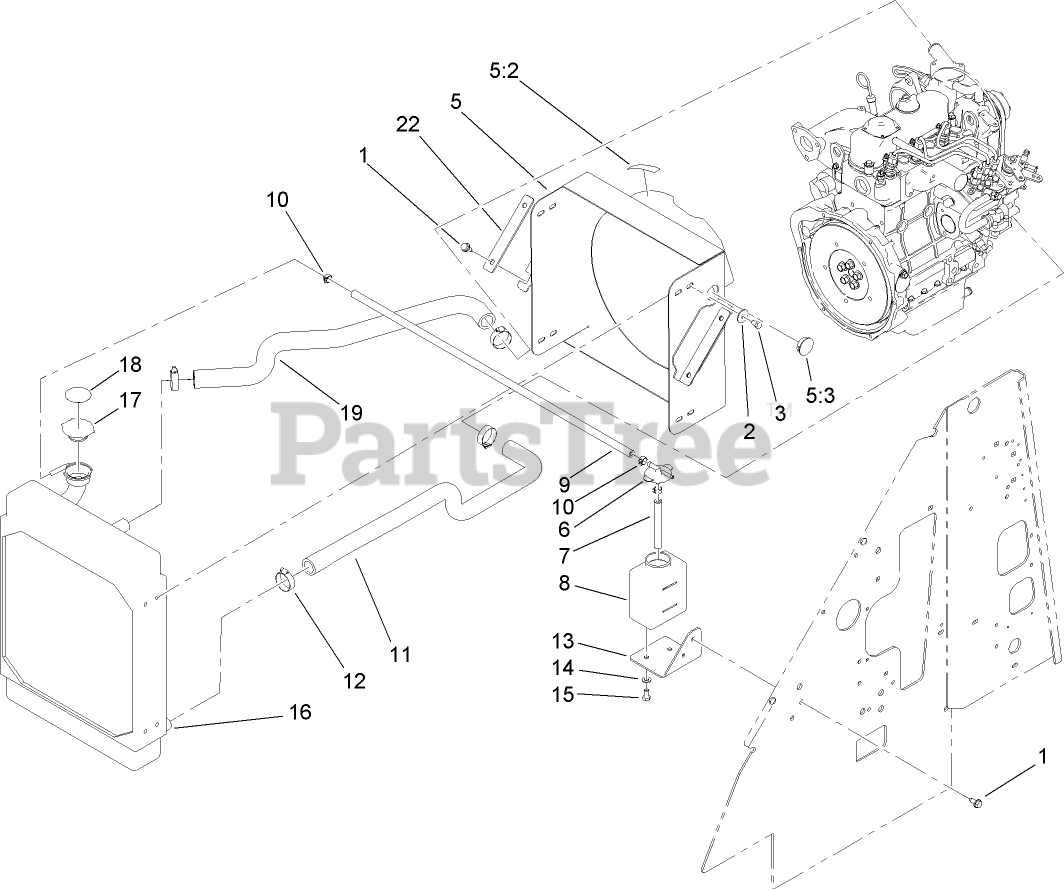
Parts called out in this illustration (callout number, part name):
1	SCREW-HWHTF
2	WASHER-FLAT
3	SCREW-HH
5	MOUNT-RADIATOR
5:2	DECAL-WARNING, FAN
5:3	PLUG-HOLE
6	CAP-TANK, OVERFLOW
7	HOSE-FUEL
8	TANK-OVERFLOW
9	HOSE-FUEL
10	CLAMP-HOSE
11	HOSE-RADIATOR, LOWER
12	CLAMP-HOSE
13	MOUNT-TANK, OVERFLOW
14	WASHER-PLAIN
15	BOLT
16	RADIATOR
17	CAP-RADIATOR
18	DECAL-WARNING
19	HOSE-RADIATOR, UPPER
22	PLATE-CLAMP, RADIATOR
